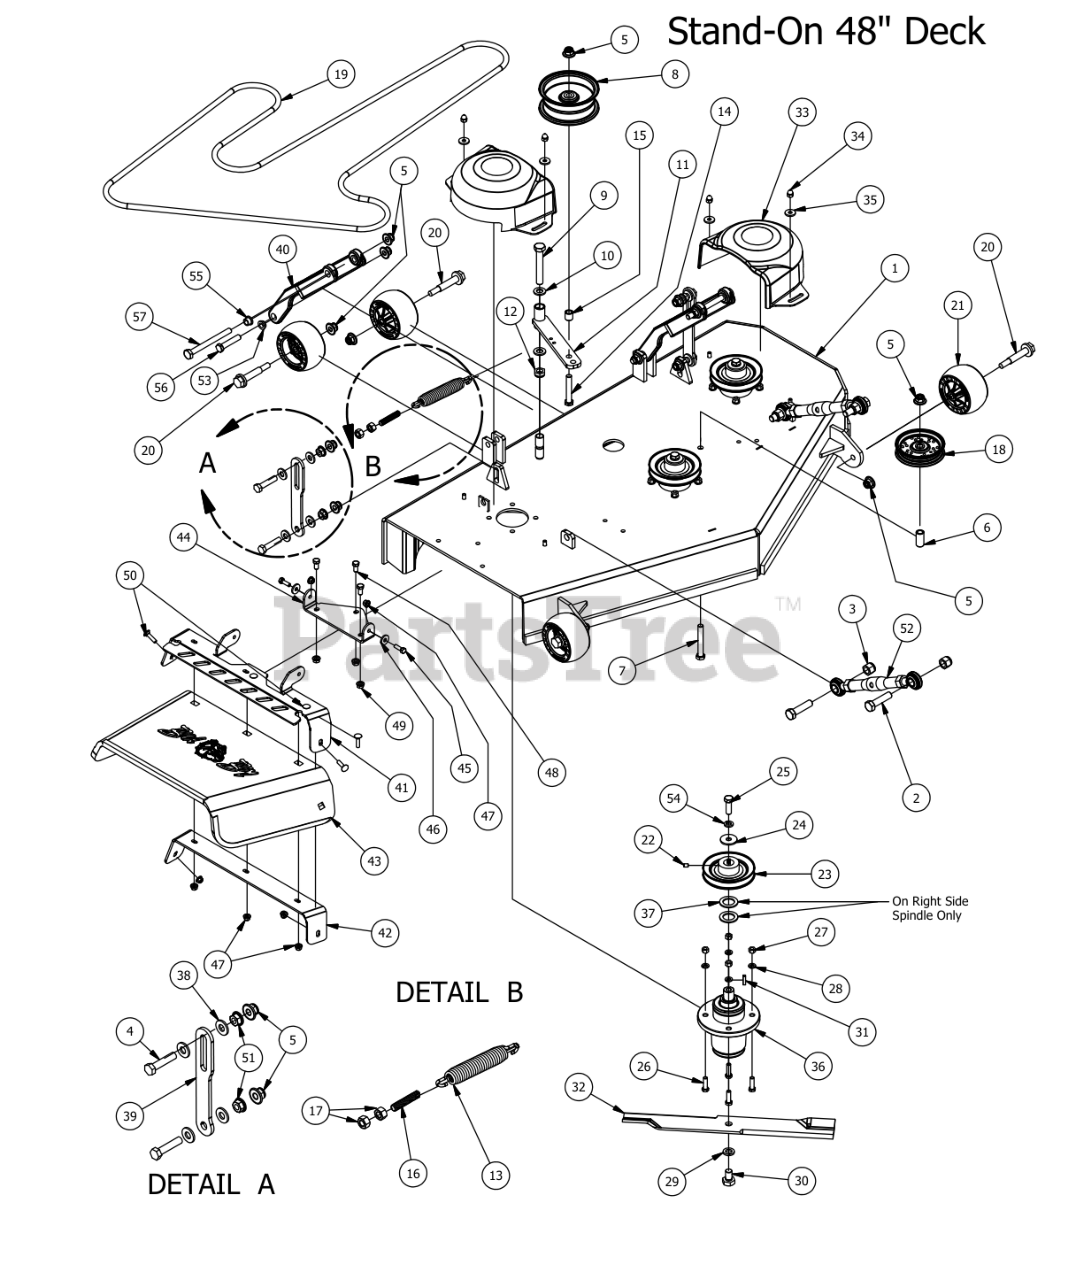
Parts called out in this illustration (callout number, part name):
1	48" 2015 Stand-On Deck (Welded Assembly)
2	5/8" x 2 1/2" Hex Bolt
3	5/8 Std NC Nylock Nut
4	1/2-13X 2-1/4 GR Hex Bolts
5	1/2-13 Nylon Flange Nut
6	.502 ID X.750 OD X 1.500 Long Spacer
7	1/2 x 3 1/2 Flange Bolt Grade 8
8	5 3/4" Deck Idler Pulley
9	5/8" x 4" Hex Bolt
10	.630 ID Plastic Washer
11	Deck Idler 2009 AOS
12	5/8" Nylock (1/2 Jam)
13	2009 Deck/Pump Idler Spring
14	1/2-13 x GR 5 Hex Bolt Zinc
15	Spacer 3/4 OD x 1/2 ID x 3\4 Length
16	All Thread-Pump Idler Tensioner
17	1/2" Hex Nut
18	4-3/4 Idler Pulley
19	B111 Belt 48" Stand-On
20	Deck Wheel Bolt
21	Anti-Scalp Rollers
22	5/16 Set Screw
23	5" Spindle Deck Pulley
24	1/2 Belleville Washer
25	1/2"-20 x 1 1/2 - Grade 5 Fine Thread Bolt
26	3/8" x 1 1/4" Hex Bolt
27	3/8-16 Hex Nuts Zinc
28	3/8" Lock Washer
29	5/8" Lock Washer
30	5/8" x 1 1/2" Grade 8 Hex Bolt (Fine)
31	1/4" x 1" Key
32	Fusion Blade
33	Pulley Cover
34	Acorn nut-pulley Cover
35	.360 ID Plastic Washer-Black
36	OUTLAW SPINDLE ASSEMBLY
37	1 1/8" Flat Spacer
38	.505 Nylon Spacer
39	Longer deck hanger
40	Deck Arm Assembly
41	Discharge Upper Chute Bracket
42	Discharge Lower Chute Bracket
43	Rubber Discharge Chute
44	Discharge Chute Hanger (Deck Mounted)
45	5/16" x 1" Bolt
46	.360 ID Plastic Washer
47	5/16" Nylon Flange Nut
48	3/8" x 3/4" Hex Bolt
49	3/8" Flange Nut
50	5/16" x 1 1/4" Carriage Bolt
51	1/2" Flange Nut
52	Turnbuckle
53	Flange Bushing For Lower Deck Arm
54	1/2" Lock Washer
55	Flange Bushing For Upper Deck Arm
56	1/2" x 3" Hex Bolt
57	1/2" x 5 1/2" Bolt
